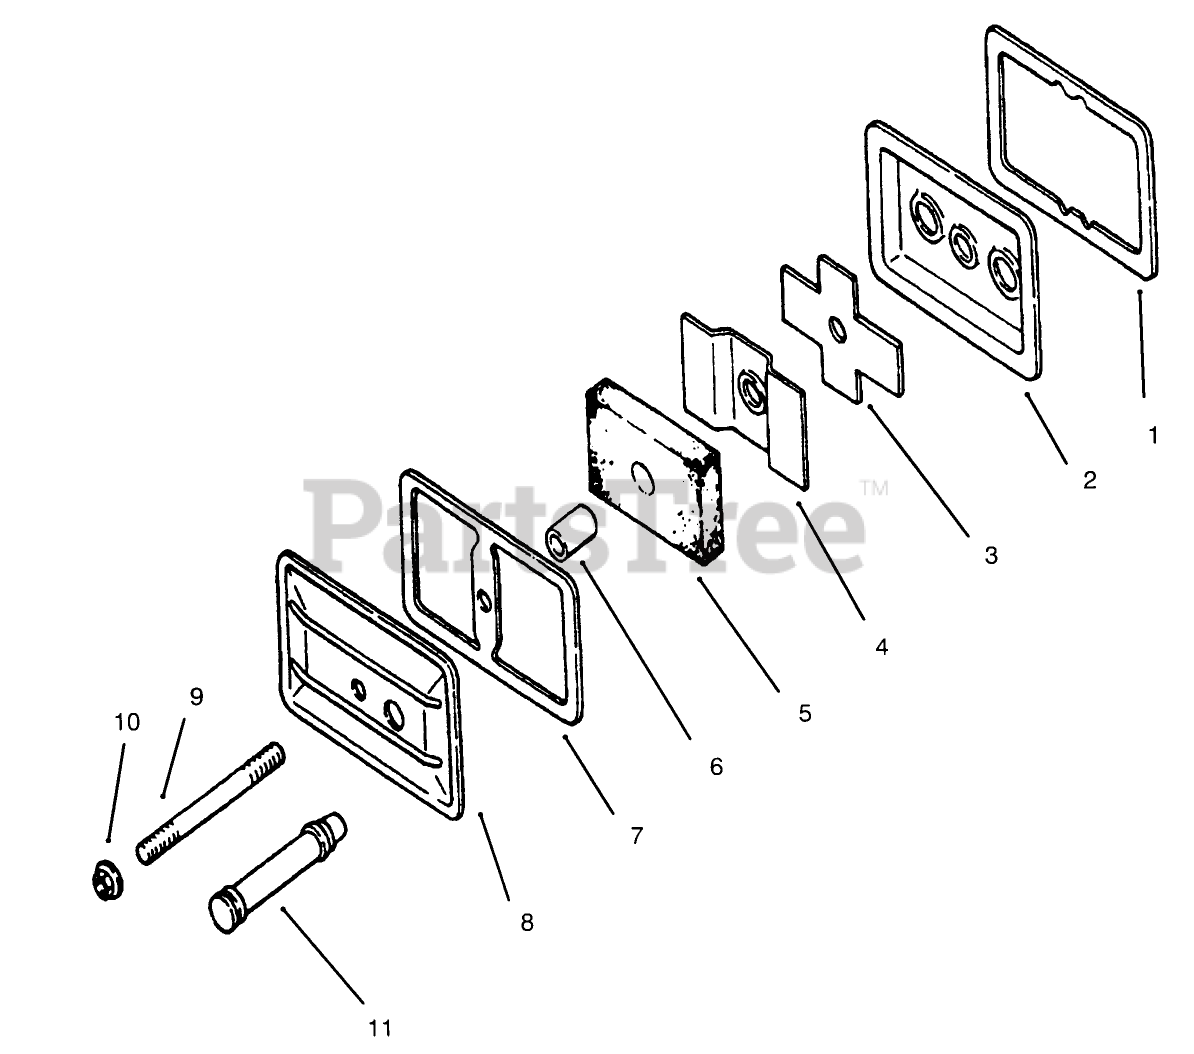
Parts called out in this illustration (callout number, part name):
1	Gasket
2	Plate
3	Reed
4	Baffle
5	Filter
6	Seal
7	Gasket
8	Cover
9	Stud
10	Palnut
11	Hose
